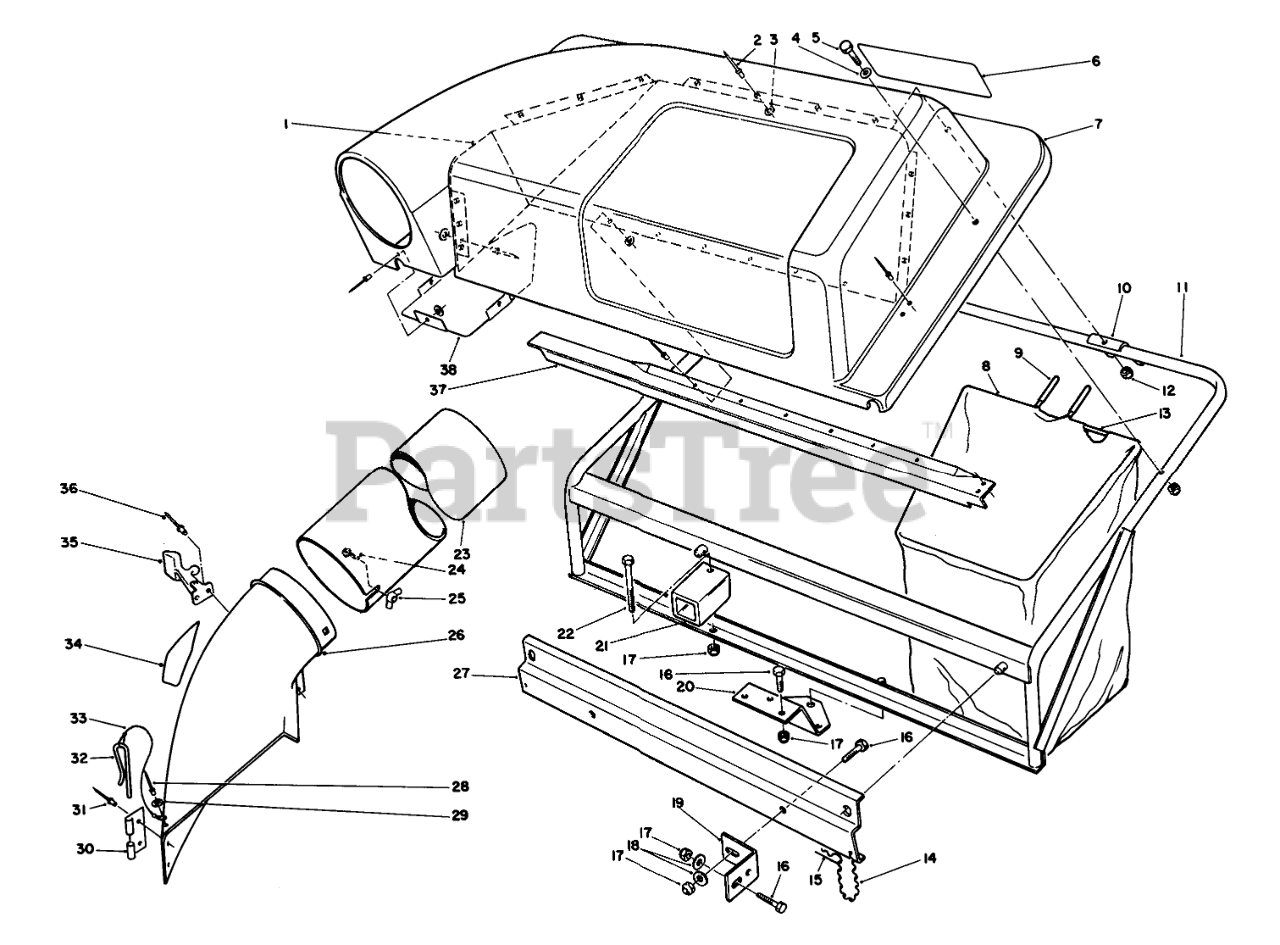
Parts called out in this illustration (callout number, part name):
1	Screen Cover
2	RIVET-POP
3	WASHER-FLAT
4	WASHER-PLAIN
5	SCREW-HH
6	TWIN BAGGER DECAL
7	Cover
9	GRIP-HANDLE, BAG
10	BAG FRAME BRKT
11	Frame
12	NUT-LOCK, CAP
13	Frame-Bag
14	6-LINK CHAIN W/HOOK
15	PIN-HAIR
16	SCREW-HH
17	NUT-LOCK, NI
18	WASHER-PLAIN
19	MTG BRACKET
20	MTG PLATE B
21	FRAME SUPT TUBE B
22	SCREW-HH
23	TUBE(ROUND&LONG)
24	BOLT-CARR
25	NUT-WING SPECL
26	Chute Assy. (Incl. Ref. #28-36)
27	Bracket Frame Support
28	RIVET-BLIND
29	WASHER-PLAIN
30	BRACKET-MOUNTING, CHUTE
31	RIVET-BLIND
32	PIN-LOCKING, CHUTE
33	LANYARD
34	DECAL-DANGER
35	Latch-38"
36	RIVET-POP
37	SCREEN SUPT BRKT B
38	Shield Cover
